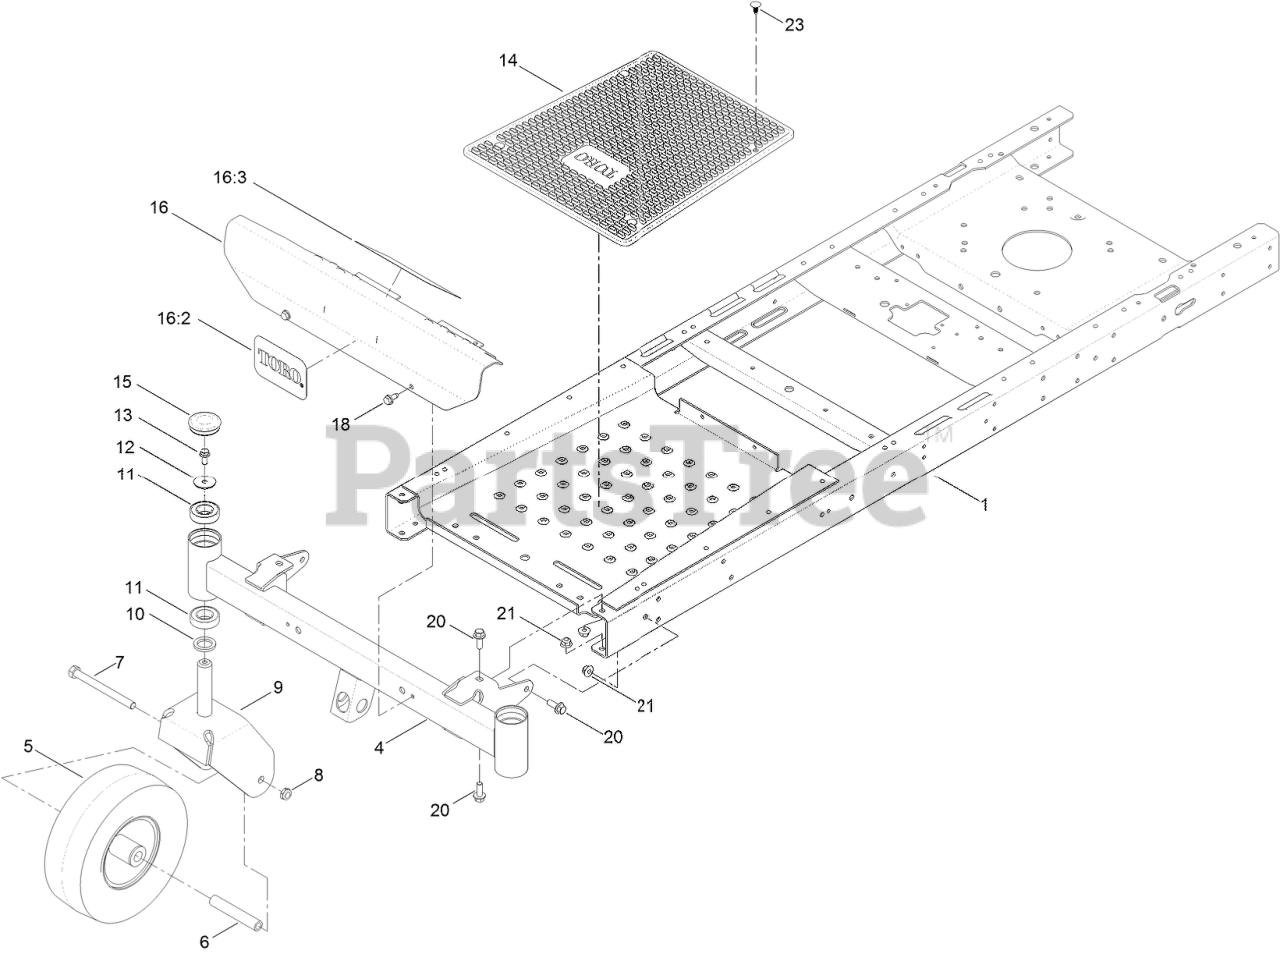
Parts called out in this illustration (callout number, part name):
1	FRAME ASM
4	AXLE-FRONT, NARROW
5	Caster Wheel ASM
6	BUSHING-SPANNER
7	SCREW-HH
8	NUT-LOCK, NI
9	FORK-CASTER
10	WASHER-THRUST
11	BEARING-BALL
12	WASHER-FLAT
13	SCREW-HHF
14	MAT-FLOOR
15	CAP-GREASE
16	FOOTREST ASM
16:3	DECAL-DANGER
18	SCREW-HWHTF
20	SCREW-HHF
21	NUT-HF, NI
23	PLUG-PLASTIC
